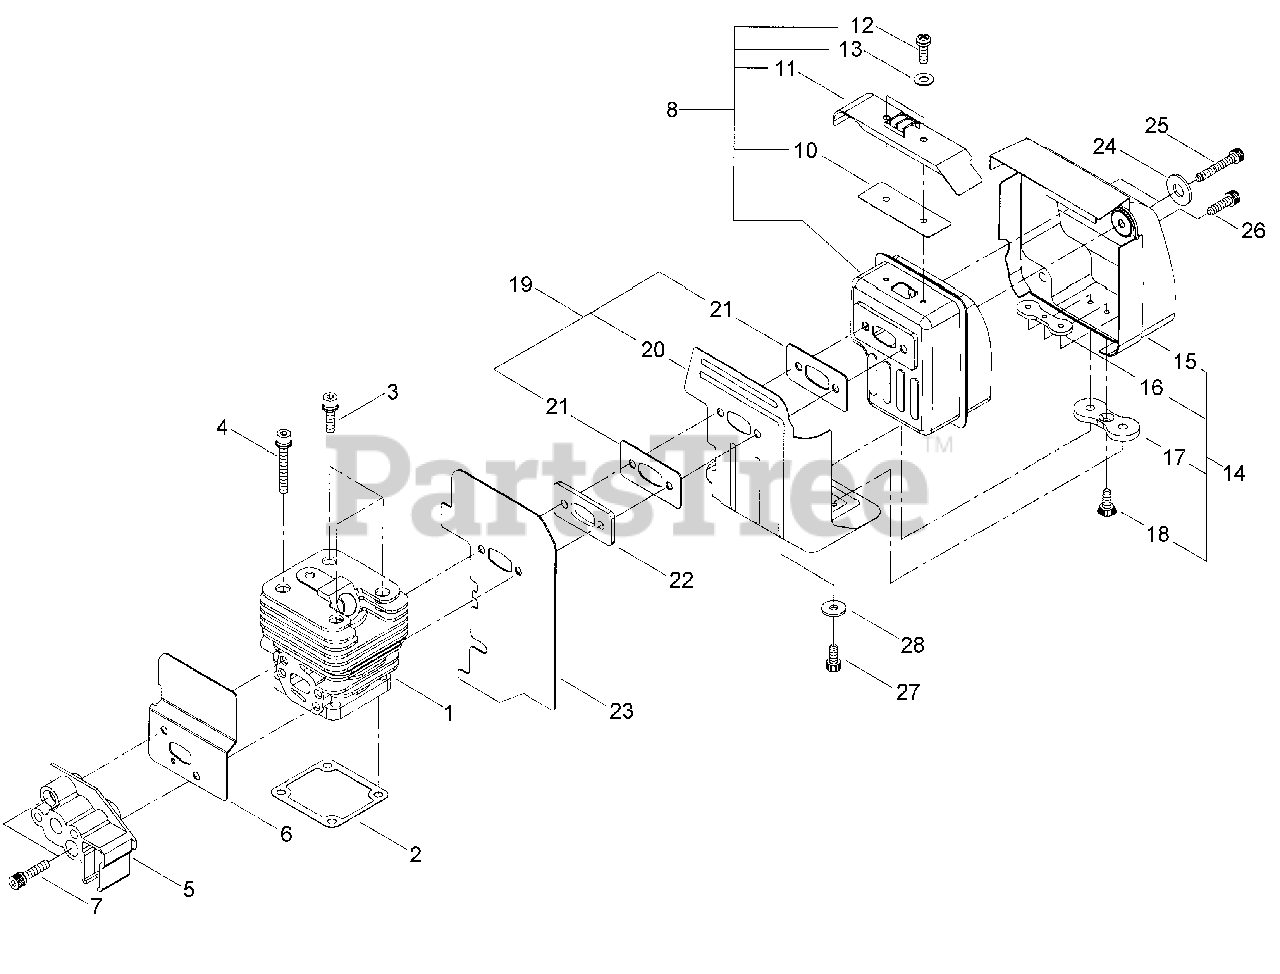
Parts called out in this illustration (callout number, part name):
1	CYLINDER
2	GASKET, CYLINDER
3	SCREW - 5X16
4	SCREW - 5X35
5	INSULATOR
6	GASKET
7	SCREW - 5X30
8	MUFFLER ASSY
10	SCREEN, SPARK ARRESTOR
11	TAIL PLATE
12	SCREW - 4X6
13	WASHER - 4
14	MUFFLER COVER ASSY
15	COVER, MUFFLER
16	PLATE
18	SCREW - 4X8
19	GASKET, EXHAUST
21	GASKET
22	SPACER
23	GASKET
24	WASHER - 5
25	SCREW - 5X65
26	SCREW - 5X25
27	SCREW - 5X10
28	COLLAR
